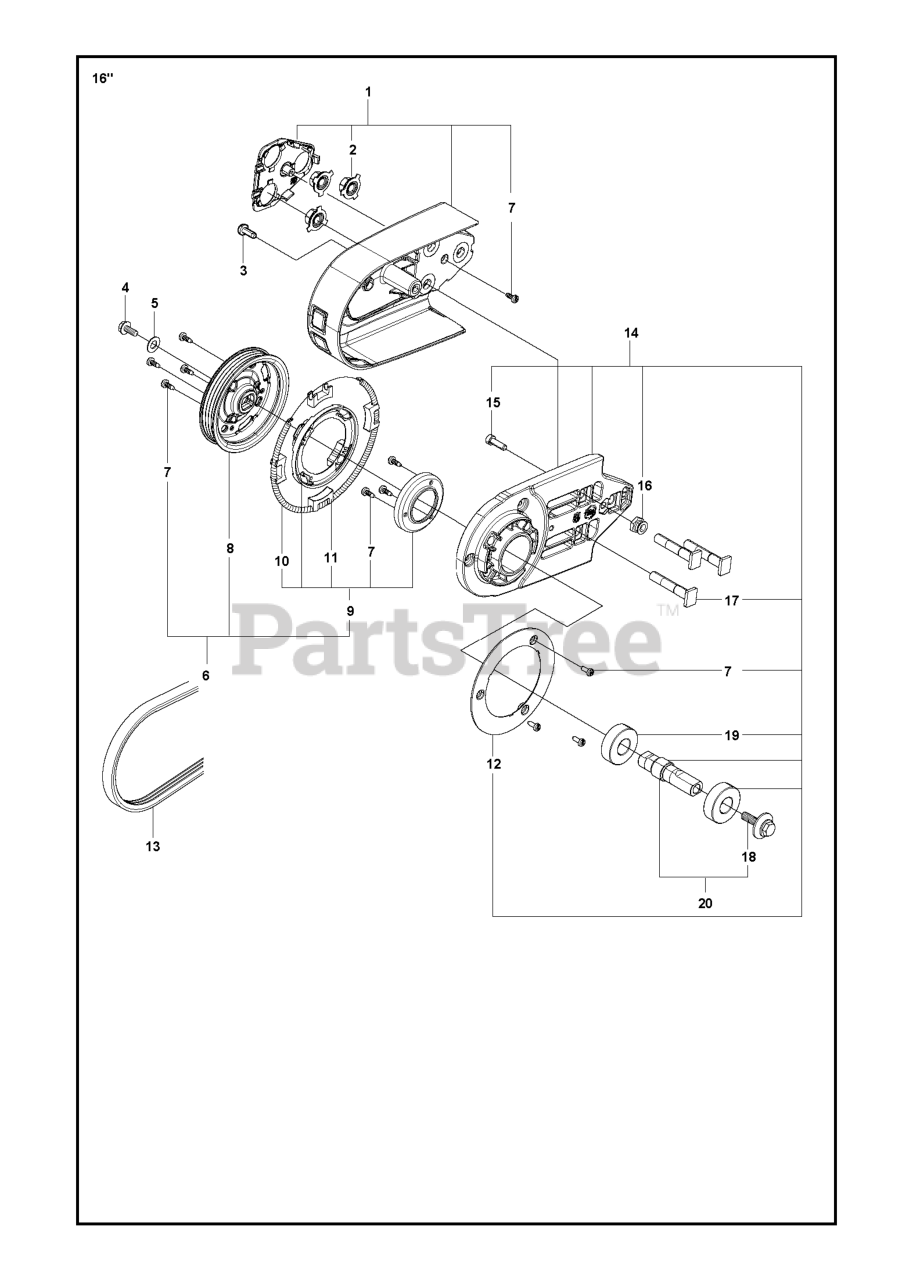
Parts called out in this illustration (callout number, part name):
1	BELT GUARD KIT 16"
2	NUT WASHER ASSY
3	SCREW ITXSCM
6	PULLEY ASSY
7	SCREW CITXPANT
8	PULLEY MACHINED PK4
9	CASSETTE FRICTION RETARDER
10	DRAW SPRING
11	BRAKE SHOE
12	SLIP RING HOLDER
13	BELT
14	BEARING HOUSING ASSY 16"
15	SCREW ITXSCM
16	STOP TORSION BEARING HOUSING
18	SCREW ASSY M10 BLADE
19	BALL BEARING
20	SHAFT KIT M10
